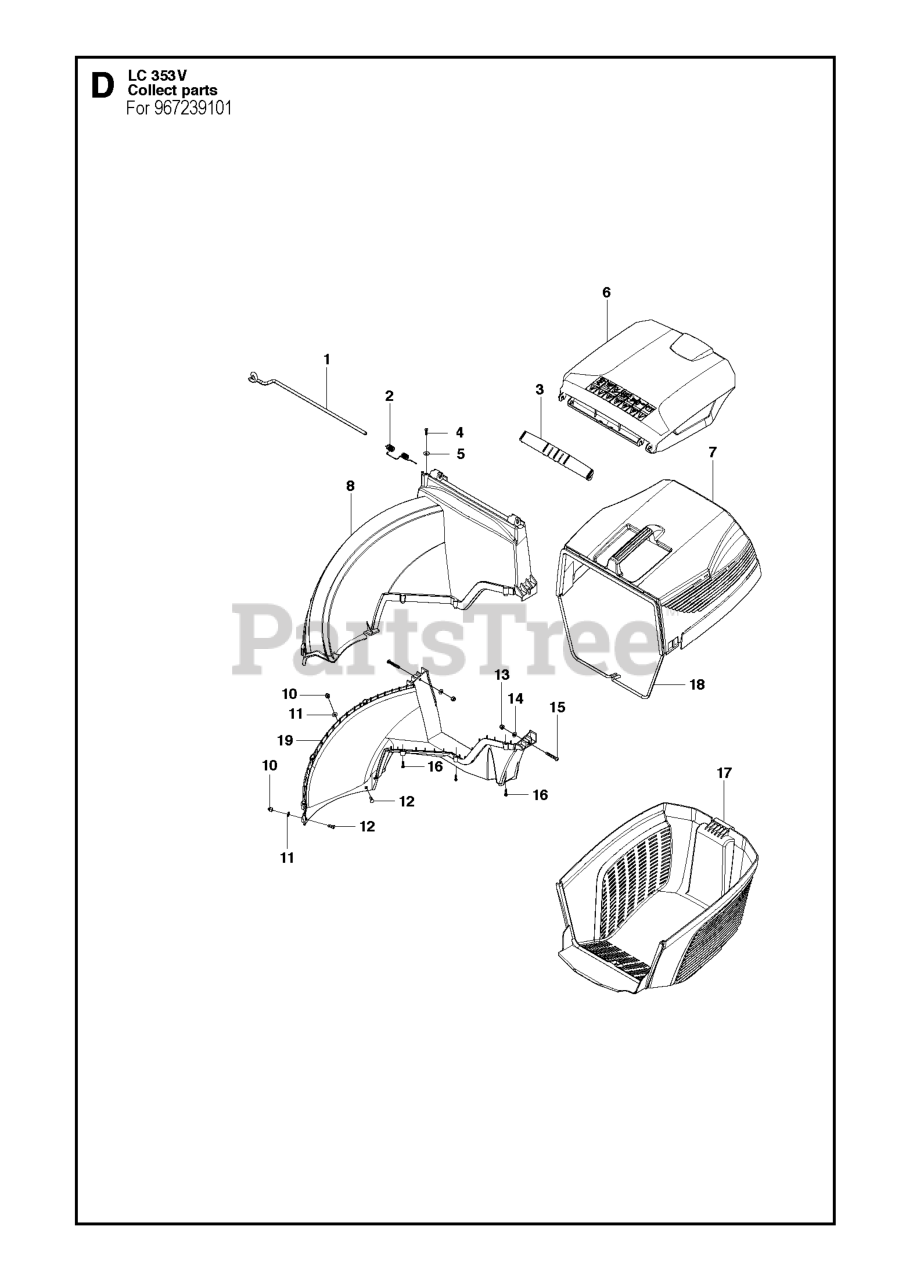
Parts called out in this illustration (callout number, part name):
1	AXLE HATCH REAR DISCHARGE
2	SPRING SAFETY FLAP A009
4	SCREW ITXPANT T50X16 ZN/FE (A
6	HATCH REAR DISCHARGE
7	GRASSBAG UPPER
13	NUT FLANGE - M6
16	SCREW ITXPANT T50X16 ZN/FE (A
17	GRASSBAG LOWER
